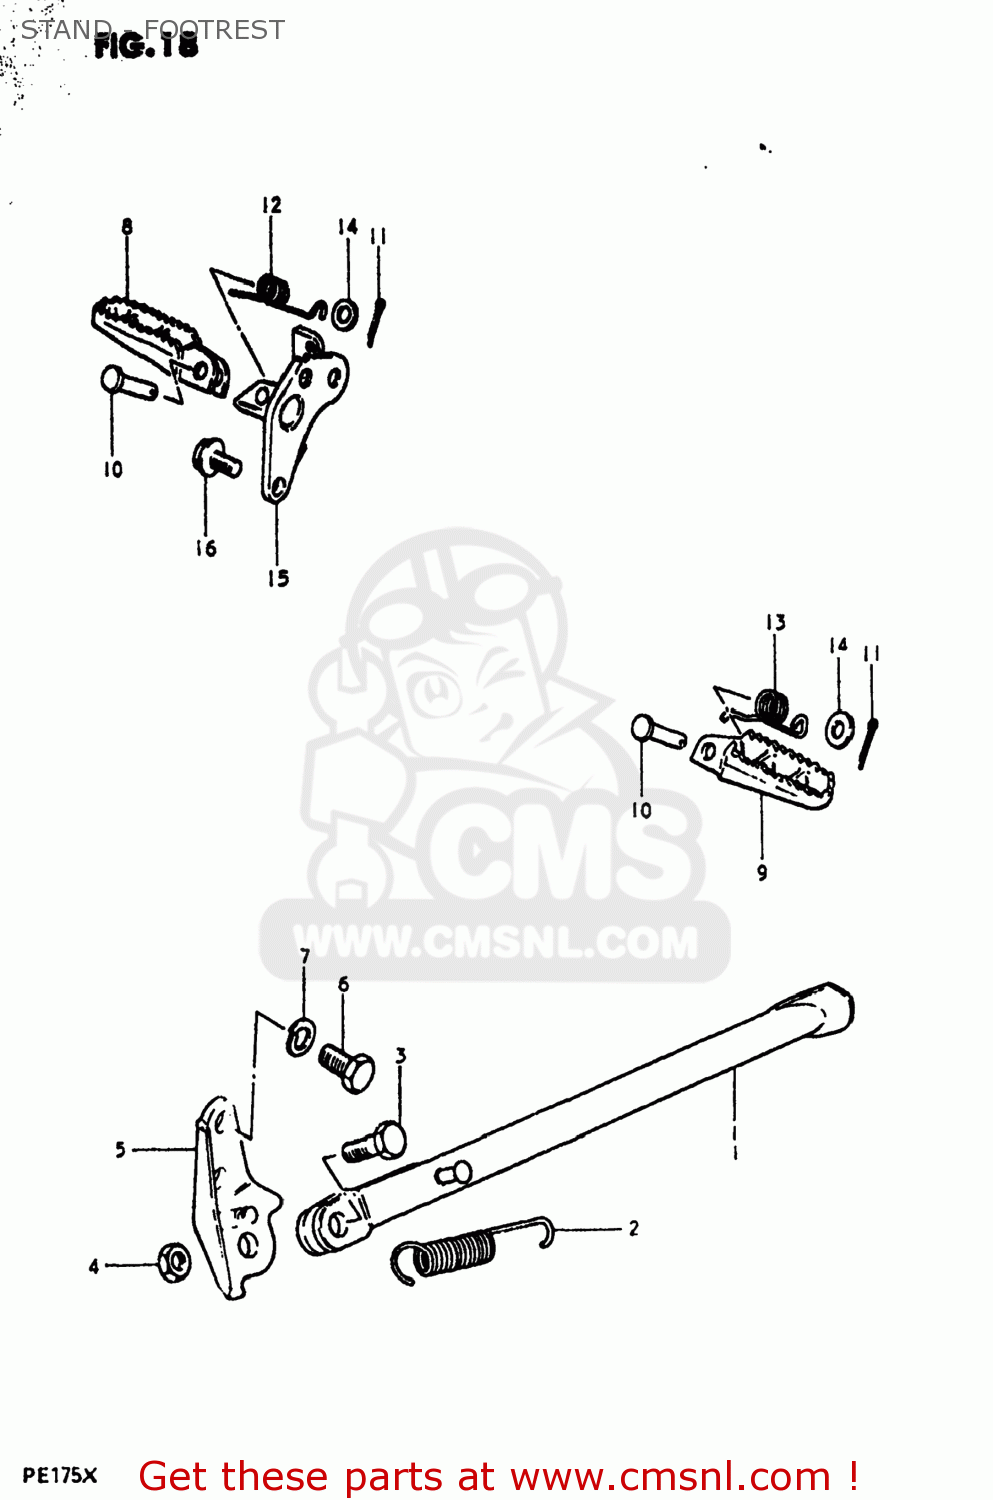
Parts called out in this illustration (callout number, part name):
1	STAND,SIDE
2	SPRING
3	BOLT(10X30)
4	NUT
5	BRACKET,PROP STAND
6	BOLT(10X19)
7	LOCK WASHER
8	RUBBER,FRONT FOOTREST
9	FOOTREST
10	PIN
11	PIN 30X20
12	SPRING
13	SPRING
14	WASHER
15	HOLDER,FRONT FOOTREST,RIGHT
16	BOLT(10X20)
